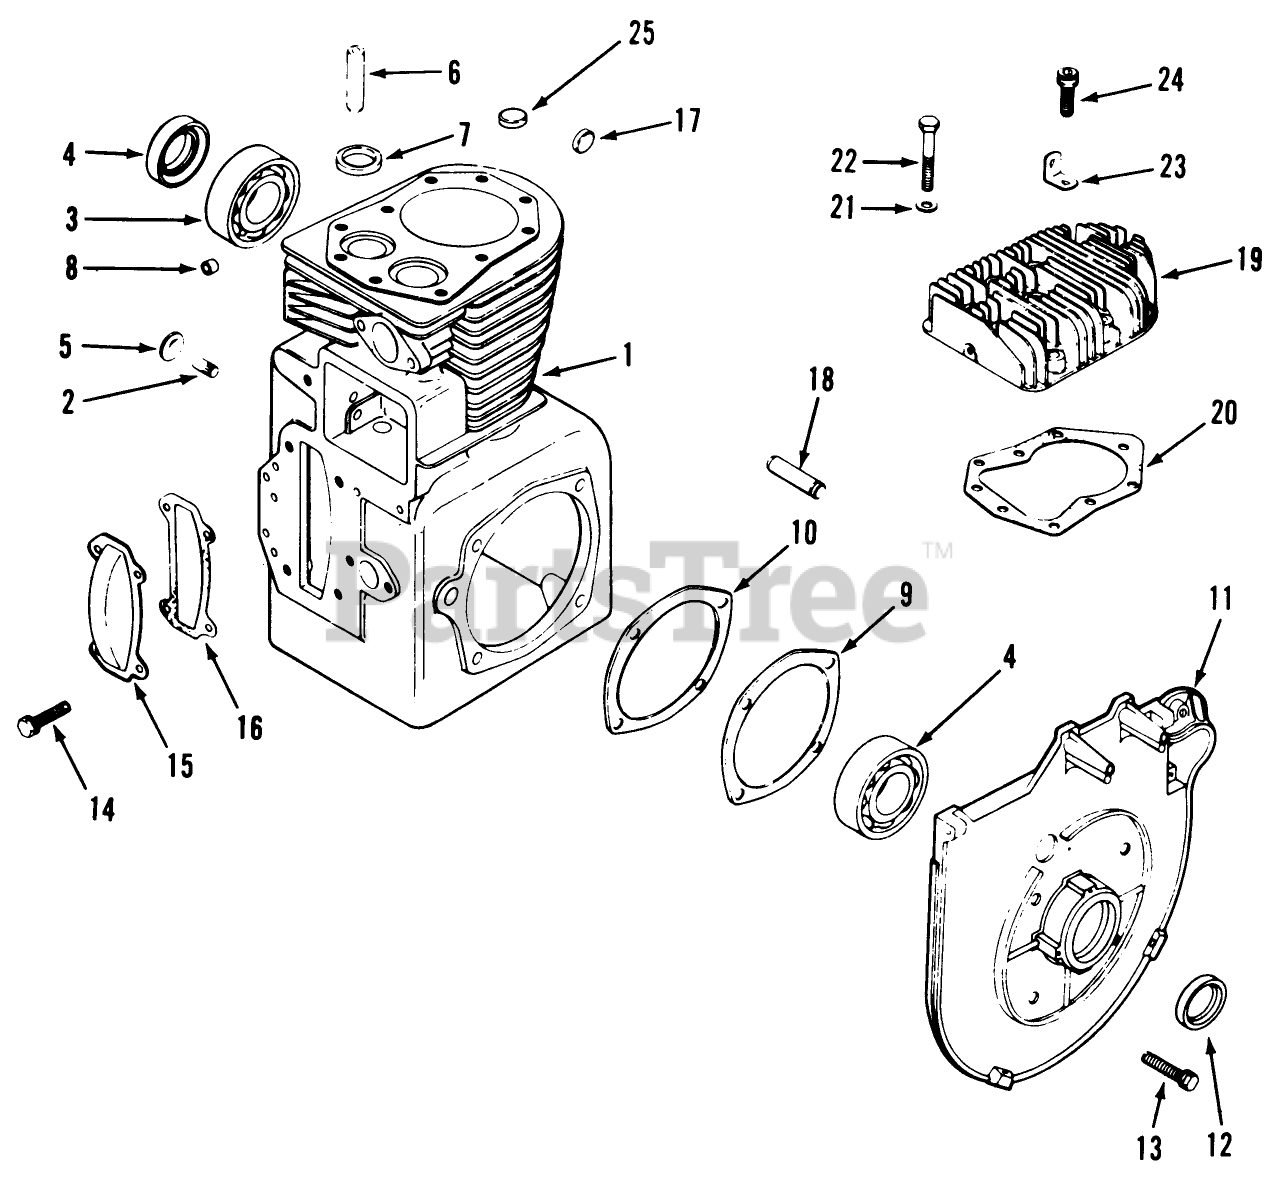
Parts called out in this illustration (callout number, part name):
1	Cylinder Block-Service With Short Block (Includes Crankshaft
2	KOHLER 235125-5
3	KOHLER 235376
4	KOHLER 47-032-07
5	KOHLER X-230-11
6	KOHLER 230007-5
7	KOHLER 230170
8	KOHLER 234866
9	KOHLER 47-041-09
10	KOHLER 47-522-05
11	KOHLER 47-146-11
12	KOHLER 47-032-06
13	KOHLER X-159-2
14	KOHLER X-132-6
15	KOHLER 235026
16	KOHLER 235025
17	KOHLER X-702-12
18	KOHLER 236559
19	KOHLER 47-015-06
20	KOHLER 47-041-15
21	KOHLER 270889
22	KOHLER 270158
23	KOHLER 47-455-02
24	KOHLER 47-086-17
25	Plug Cup (310 only)
